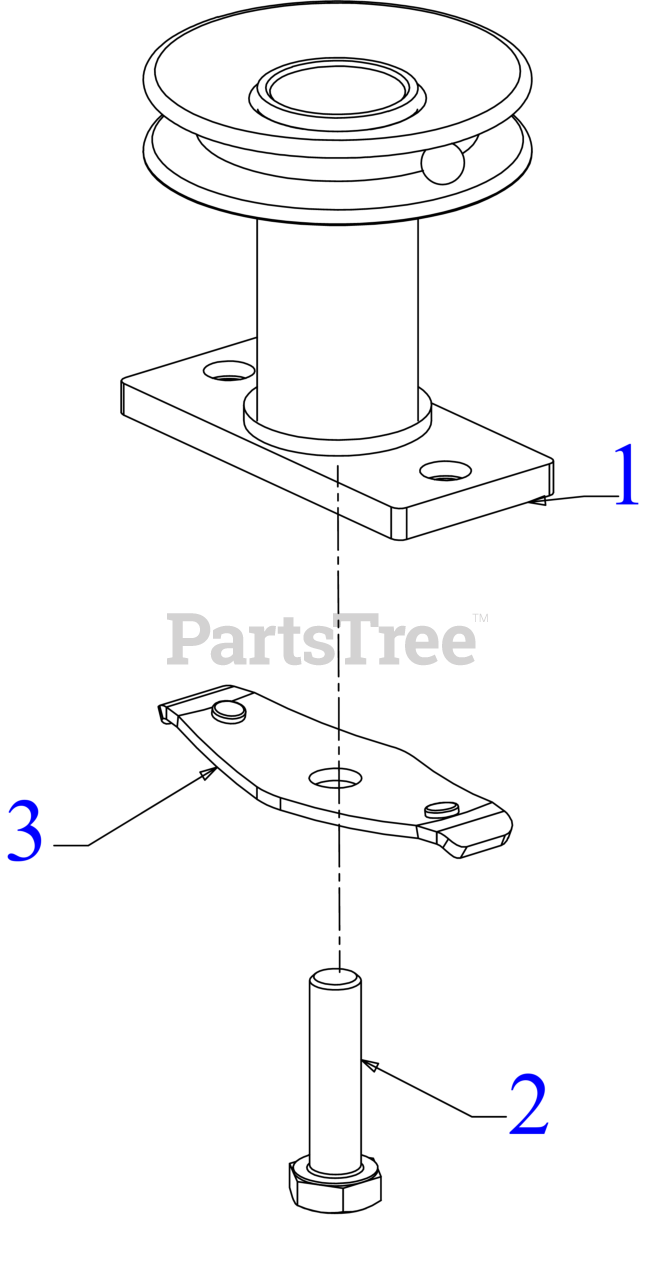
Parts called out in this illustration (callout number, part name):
1	ADAPTER ASSEMBLY-7/8"
2	SCREW 3/8-24 x 1.50 GR8
3	BLADE BELL SUPPORT
